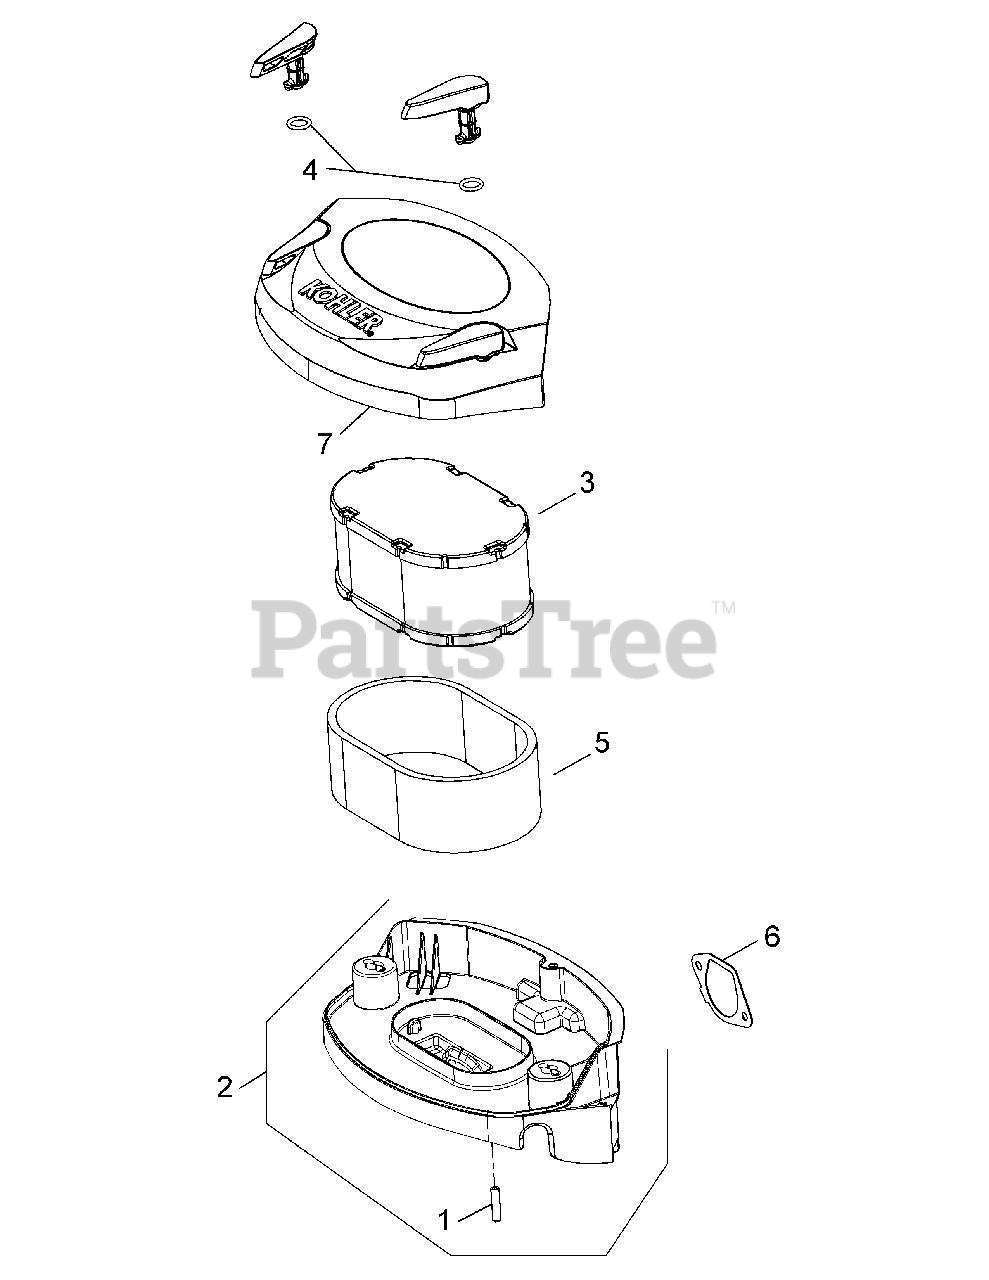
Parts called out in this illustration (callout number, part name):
2	Air Cleaner Base Assembly
3	Air Filter Element
5	Pre-Cleaner Element
6	Air Cleaner Base Gasket
7	Air Cleaner Cover Assembly
